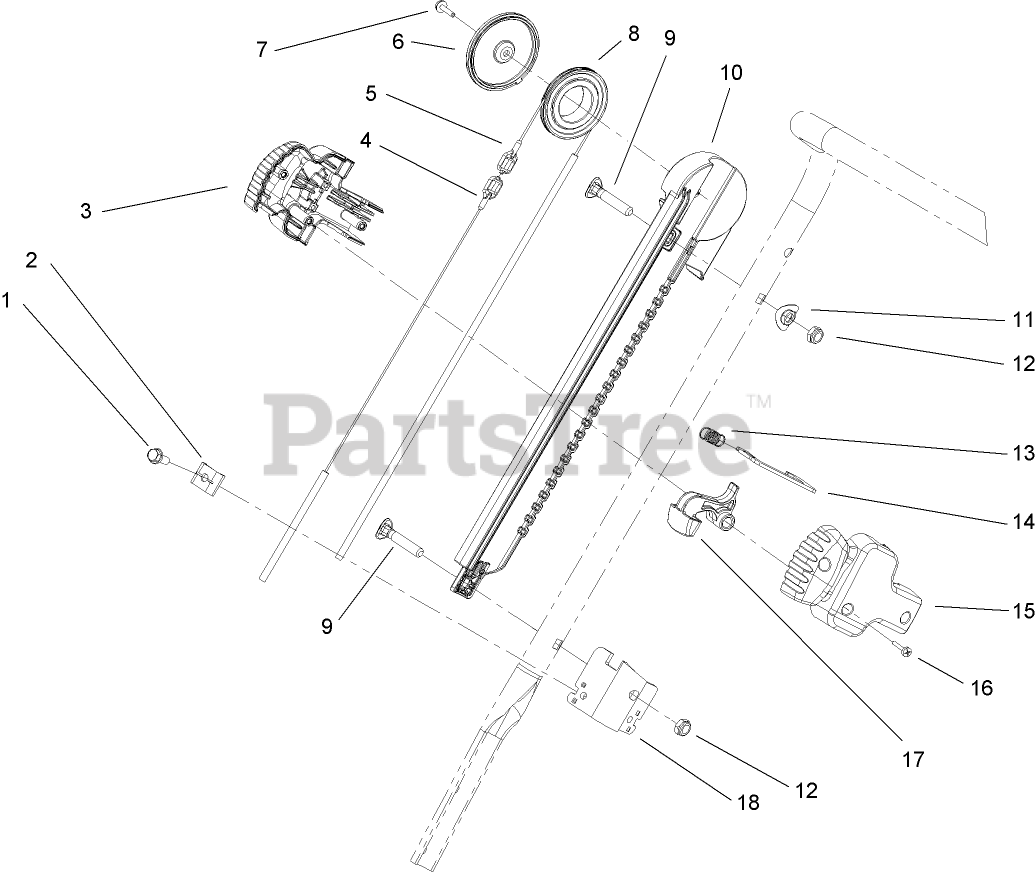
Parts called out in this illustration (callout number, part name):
1	SCREW-HWH
2	CLAMP-CABLE
3	HANDLE-SLIDER, RH
4	CABLE-CHUTE, SHORT
5	CABLE-CHUTE, LONG
6	COVER-PULLEY
7	SCREW-HWH
8	PULLEY-SLIDER
9	SCREW-HANDLE
10	TRACK-SLIDER
11	WASHER
12	NUT-LOCK, NI
13	SPRING-TRIGGER
14	PLATE-LOCK, CHUTE
15	HANDLE-SLIDER, LH
16	SCREW-PPH
17	TRIGGER
18	BRACKET-CABLE
